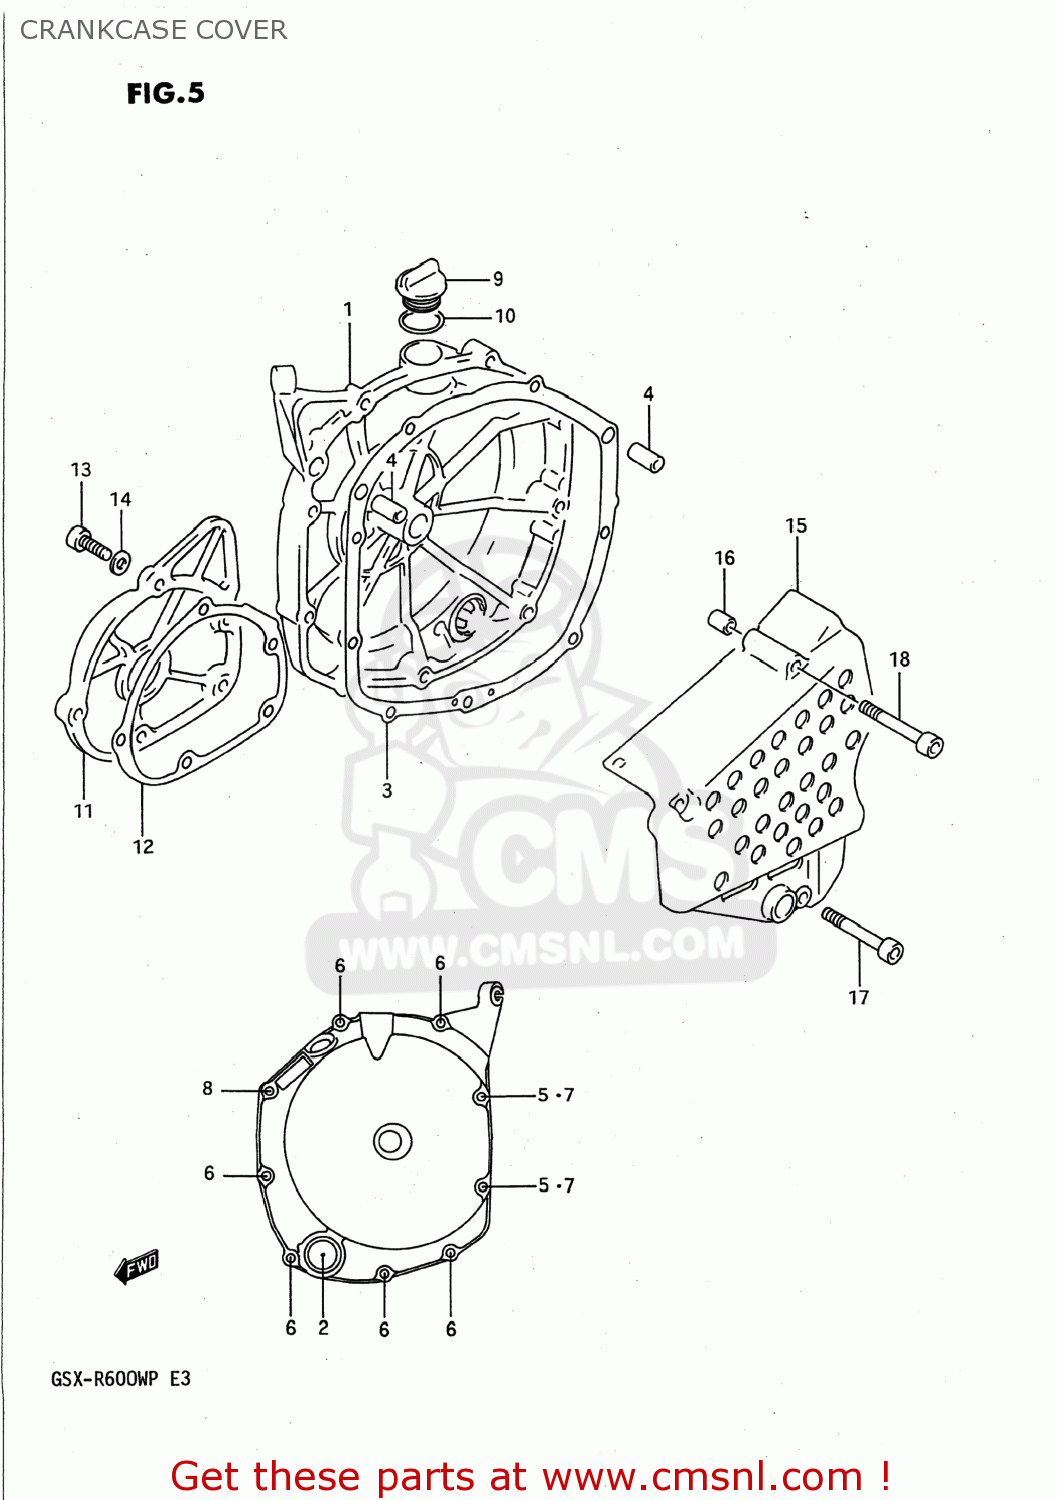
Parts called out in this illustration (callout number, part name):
1	COVER,CLUTCH
2	LENS,OIL LEVEL CHECK
3	GASKET,CL COVER (NAS)
4	PIN
5	GASKET(5.8X11X1.2) (NAS)
6	BOLT
7	BOLT
8	BOLT
9	PLUG
10	O RING(D:3.1,ID:16.8)
11	CAP
12	GASKET,SIGNAL GENERATOR COVER
13	BOLT
14	GASKET(5.8X11X1.2) (NAS)
15	COVER,SPROCKET
16	PIN
17	BOLT
18	BOLT
